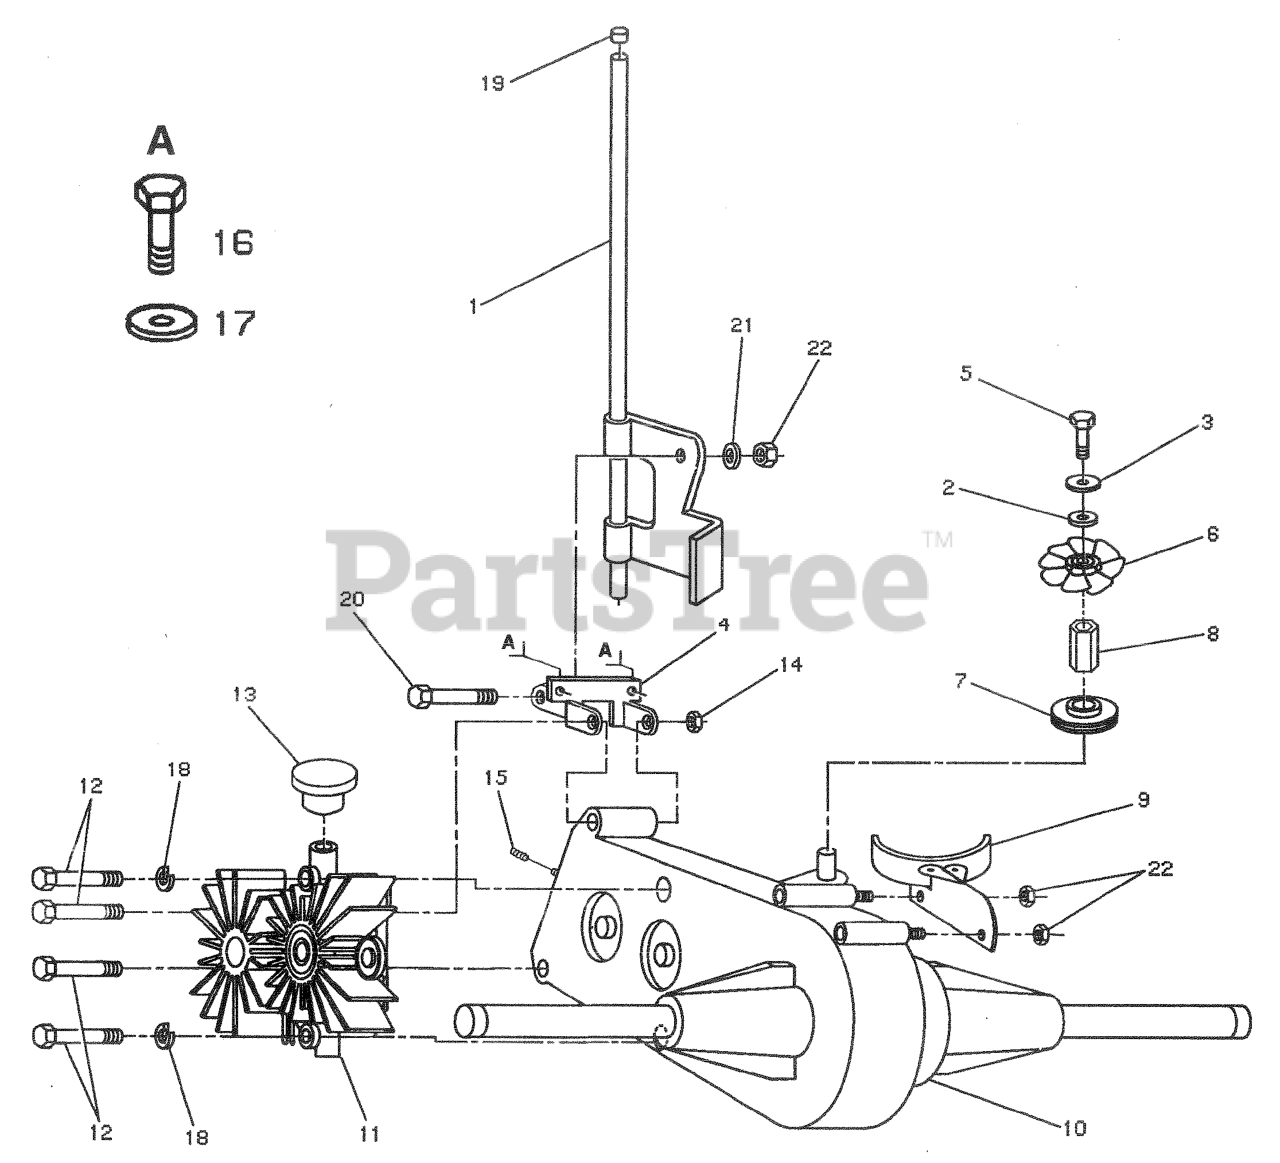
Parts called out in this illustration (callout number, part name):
1	Free Wheel Control Assembly
2	Washer 9/32 x 1 -1/4 x 16 Gauge
3	Washer, Lock 1/4
4	Bracket, Pnt., Mounting, Differential
5	Bolt, Hex 1/4-20 UNC x 3/4
6	Fan, Hydro, 8"
7	Pulley, Transaxle
8	Standoff, Fan, Hydro
9	Guard Assembly, Belt
10	Differential Assembly
11	Pump Assembly
12	Bolt, Hex, Fin 5/16-18 UNC x 4-1/2
13	Reservoir, Pump
14	Nut, Crownlock 5/16-18
15	Spring, Compression
16	Bolt, Hex 3/8-16 x 3/4
17	Nut, Crownlock 3/8-16 UNC
18	Washer, Lock 5/16
19	Cap
20	Bolt, Shoulder 1/4-20 UNC
21	Washer, Nylon
22	Nut, Crownlock 1/4-20 UNC
